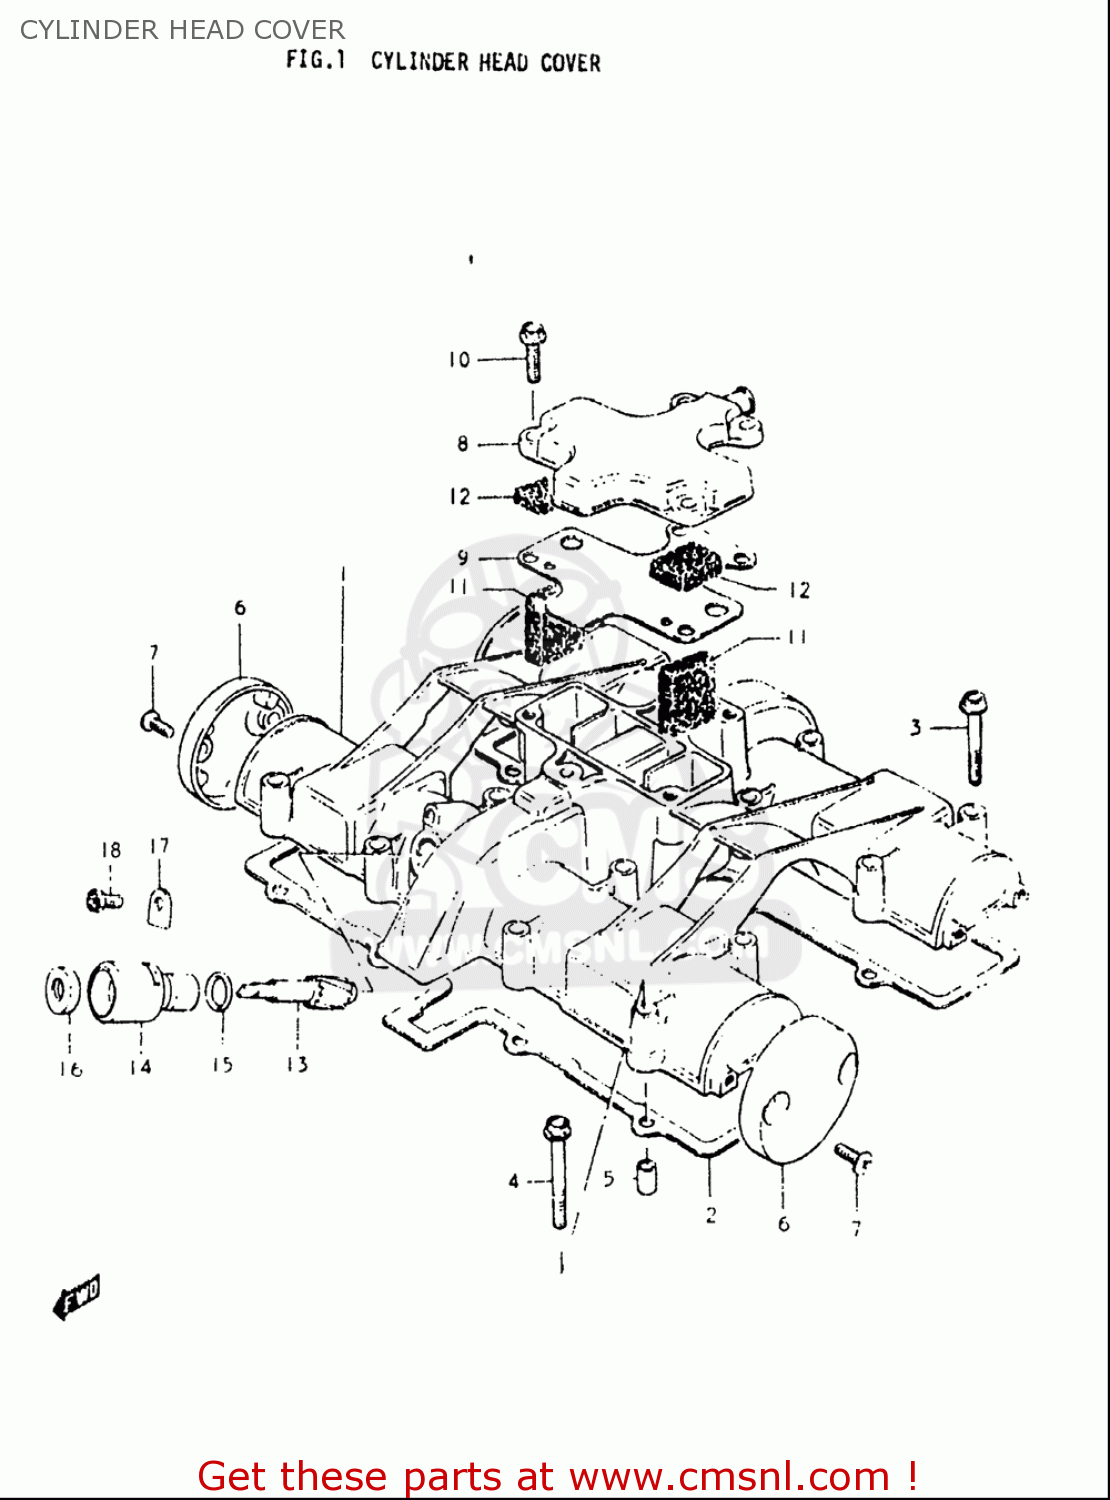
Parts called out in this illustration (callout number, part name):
2	GASKET,CYLINDER HEAD COVER (NAS)
3	BOLT
4	BOLT
5	PIN(6.2X8X11)
6	CAP,CYLINDER HEAD COVER
7	SCREW
8	COVER,BREATHER
9	GASKET,BREATHER COVER (NAS)
10	BOLT
11	SEPARATOR,OIL BREATHER
12	SEPARATOR,OIL BREATHER
13	GEAR,TACHOMETER DRIVEN
14	SLEEVE,TACHOMETER DRIVE GEAR
15	SEAL,TACHOMETER DRIVEN
16	SEAL,OIL(5X12X8)
17	PLATE,TACH DRIVE GEAR SLEEVE
18	SCREW(5X12)
